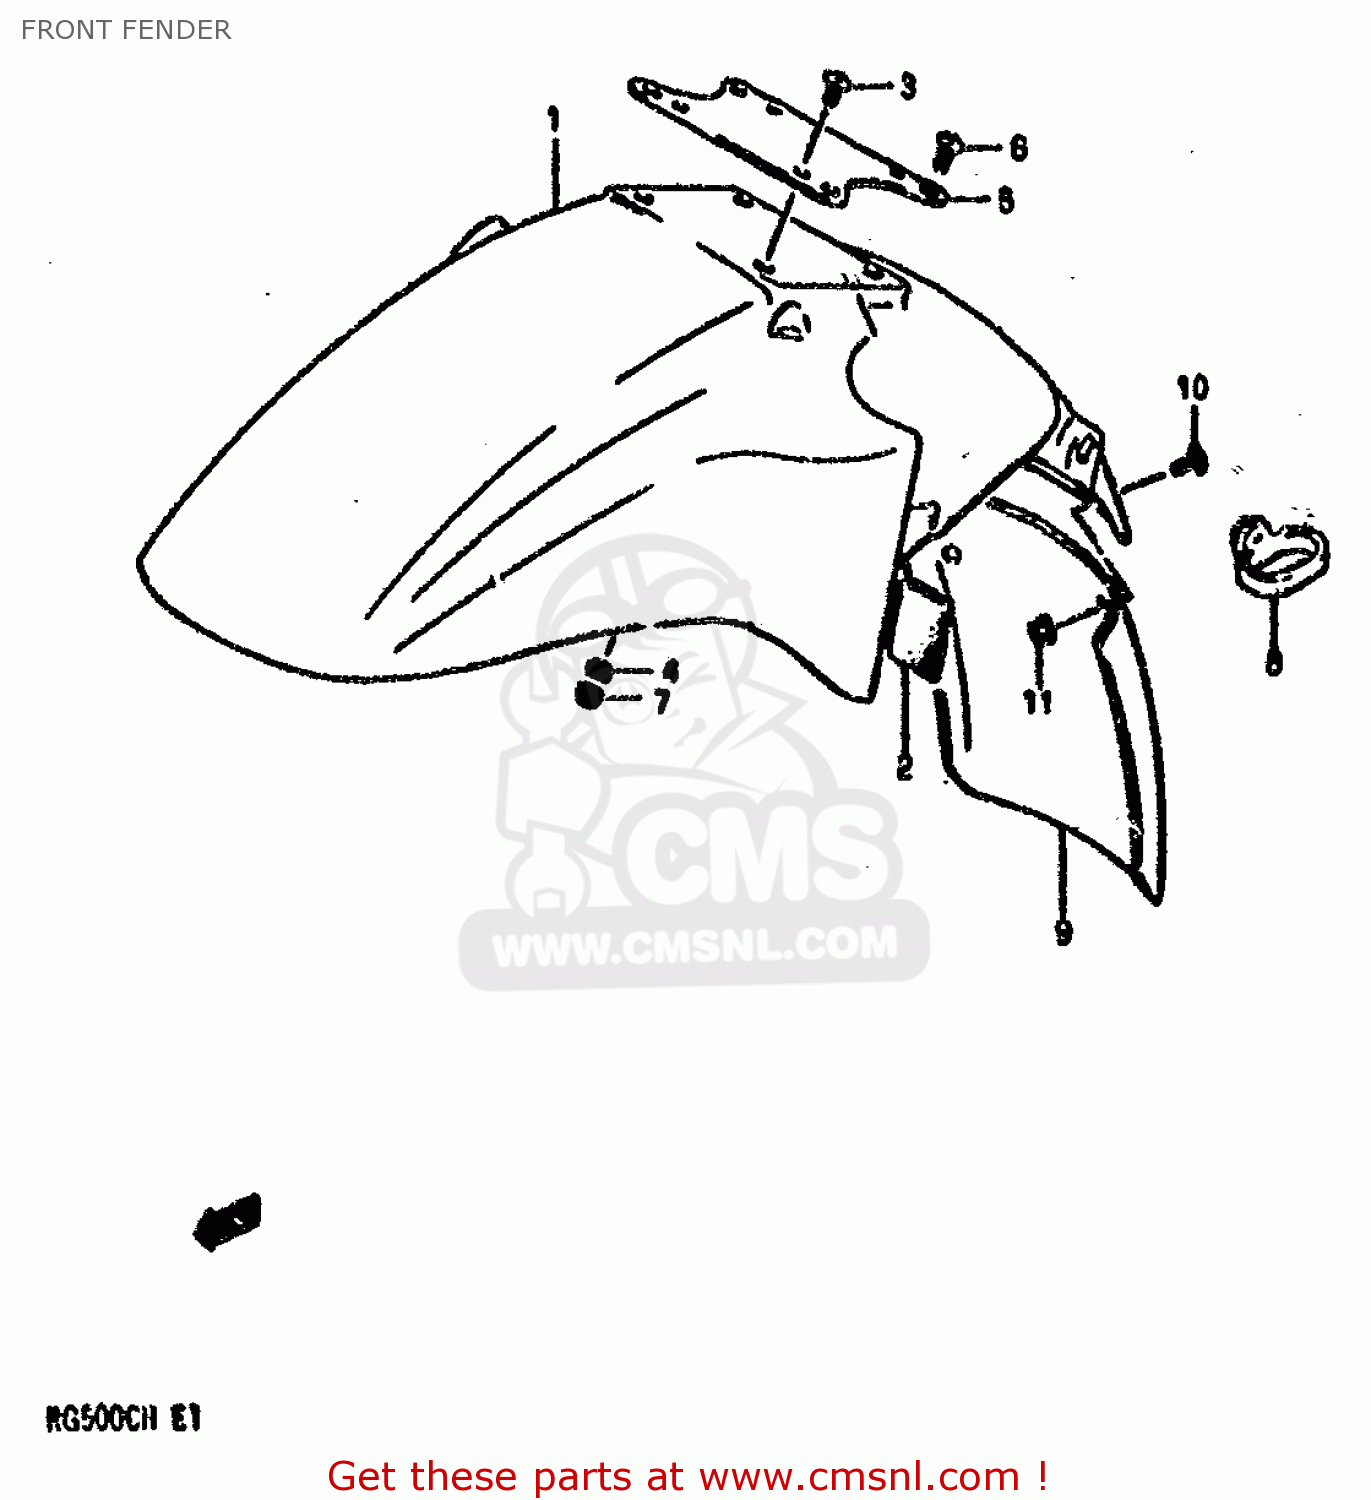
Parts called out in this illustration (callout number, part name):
1	FENDER,FRONT (WHITE)
2	CUSHION,FR FENDER
3	SCREW(5X14)
4	WASHER
5	BRACE,FRONT FENDER
6	SCREW(6X12)
7	NUT
8	GUIDE,CABLE
9	EXTENSION,FRONT FENDER
10	SCREW, FRONT & REAR
11	NUT
